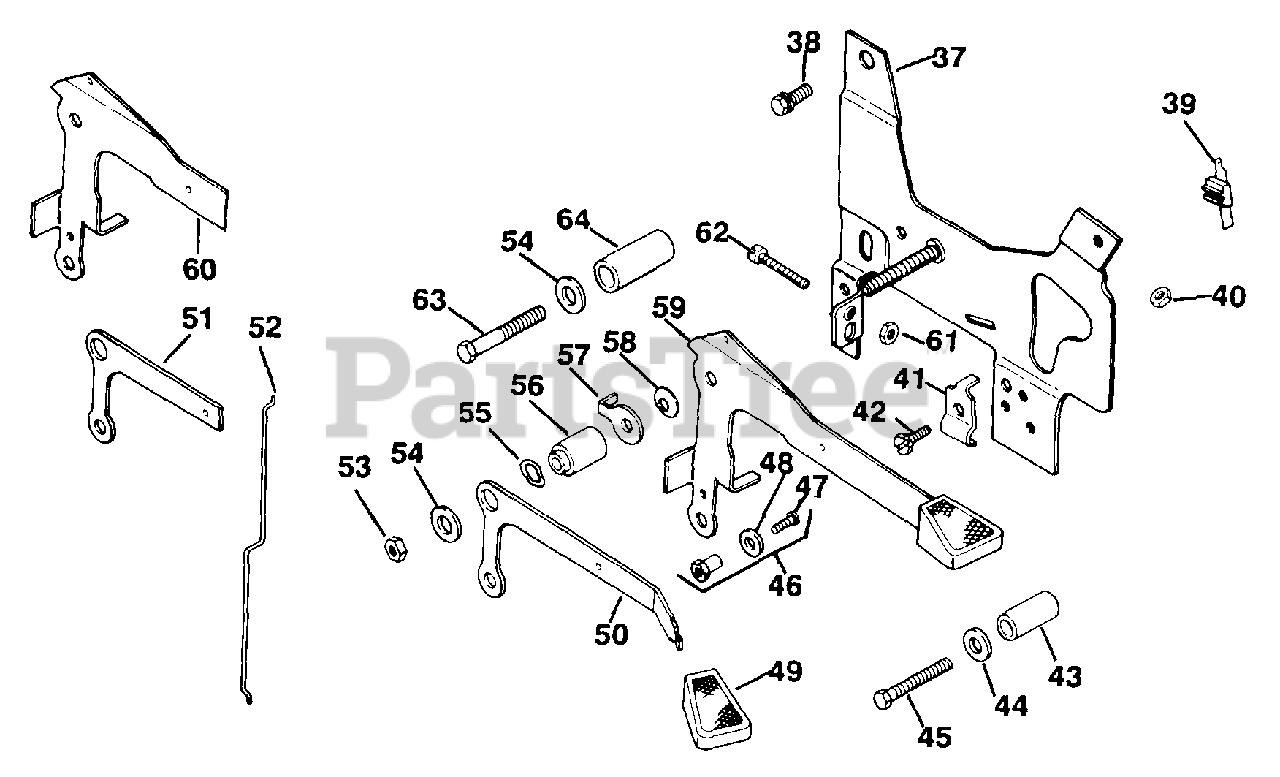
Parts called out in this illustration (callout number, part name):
37	KIT - USE 41 755 31
38	SCREW, SEMS 1/4-20-1/2"
42	SCREW, IND SLT HD 10-24X3/8" USE 25 086 79-S
54	WASHER, FLAT 1/4" (O.D. 5/8")
55	WASHER, SPRING 1/4"
57	TAB - USE 52 448 02
58	WASHER, SPRING 7/16" - DISCONTINUED
61	NUT, MACH SCREW #8-32 GRD 2 USE 25 100 16-S
62	SCREW, SLT FLS 8-32X1"
